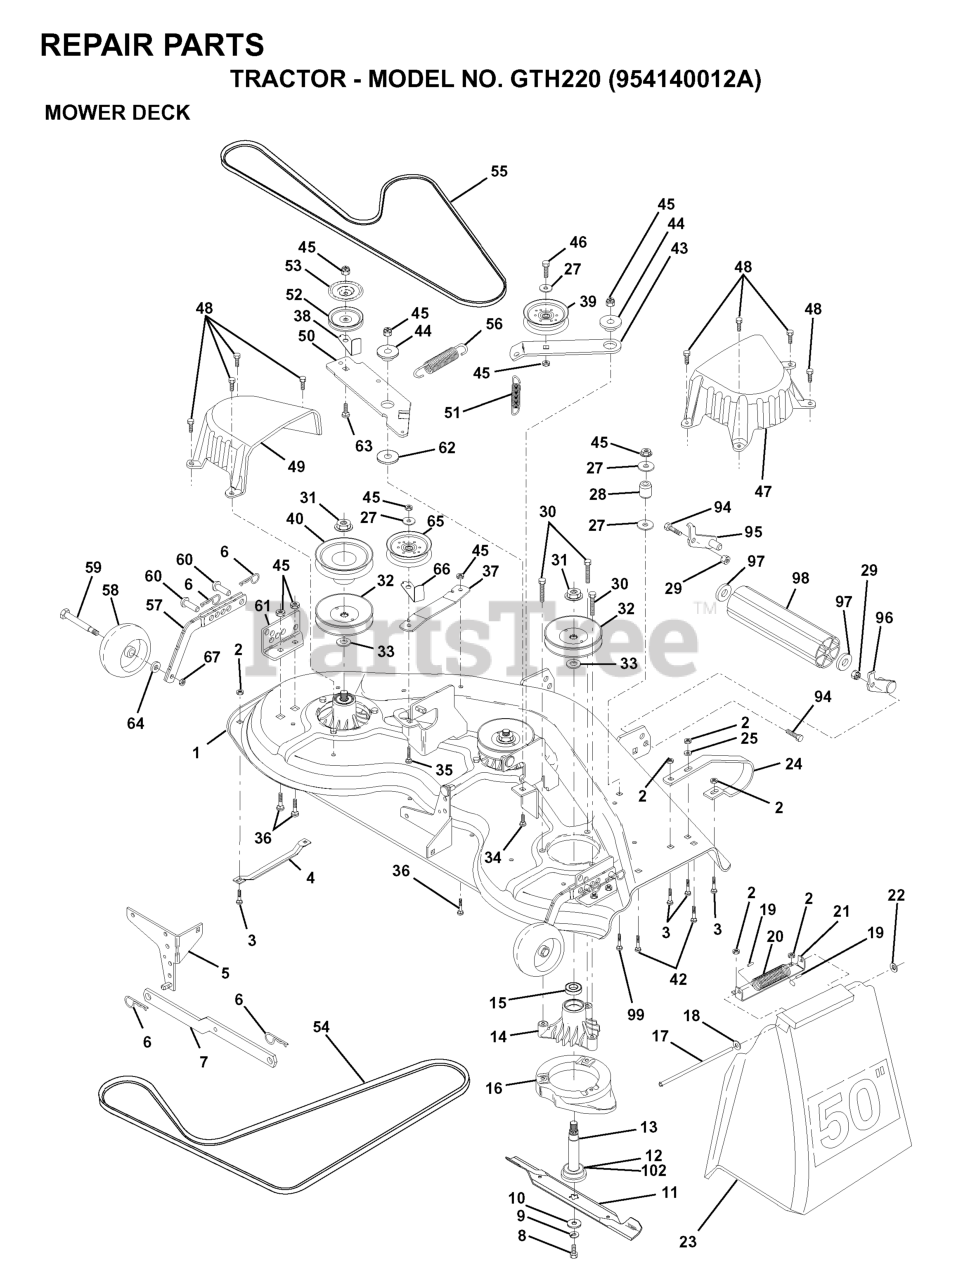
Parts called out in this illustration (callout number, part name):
1	DECK ASM MWR 50VT
2	LOCKNUT
3	BOLT.CARR.SQNK.5/16-18UNC.X3/4
4	RUNNER-LH M
5	BRACKET SWAY BAR
6	RETAINER-SPRNG RB
7	REAR SUSP ARM
8	BLADE BOLT
9	LOCKWASHER
10	WASHER.BLADE
11	BLADE.50".HI-LIFT
12	BEARING.BALL.#6204.(MANDREL)
13	SHAFT.ASM.W/BEARING
14	HOUSING.MANDREL.44/46" VENT
16	STRIPPER
17	ROD-HINGE T
18	Washer 11/32 x 5/8 x 16 Ga SD
19	CAP-SLEEVE LT
20	SPRING TORSION
21	BRACKET, DEFLECTOR
22	NUT PUSH M
23	SHIELD.DEFLECTOR.MOWER.50"BLK.
25	WASHER M
27	WASHER
28	IDLER SPRING SPACER
29	NUT
30	SCREW
31	NUT
32	PULLEY/MANDREL
33	WASHER
34	BOLT.3/8-14X1.25
36	BOLT D
37	STIFFENER ARM
38	KEEPER
39	FLAT IDLER PULLEY
40	PULLEY.DRIVEN.44"
42	RP BOLT 5/16-18 X3/4 ZN/YEL GR
43	ARM.IDLER.SEC.44"
44	SPACER RETAINER
46	BOLT
47	COVER MANDRELL
48	SCREW.1/4-20X5/8
49	COVER.MANDREL.LH.44"
50	ARM.IDLER.PRIMARY
51	SPRING.SEC.44"VEN
52	PULLEY IDLER
53	SHIELD IDLER
54	V-BELT.PRMRY 46/50 VENT.BLK BK
55	BELT V SECONDARY
57	BAR.ASM.GUAGE.WHEEL
58	WHEEL GAGE DONUT
59	BOLT, SHOULDER
60	PIN.CLEVIS
61	BRACKET.GUAGE.WHEEL
62	HARDENED WASHER
63	BOLT.3/8-16X1.50
64	WASHER.5/16.FLAT.STE.STD.
66	KEEPER
67	LOCKNUT
94	BOLT
95	BRACKET LH (A)
96	BRACKET RH (B)
97	Washer 1 17/32 X 7/8 X 16 Ga
98	NOSE ROLLER
102	WASHER FELT
